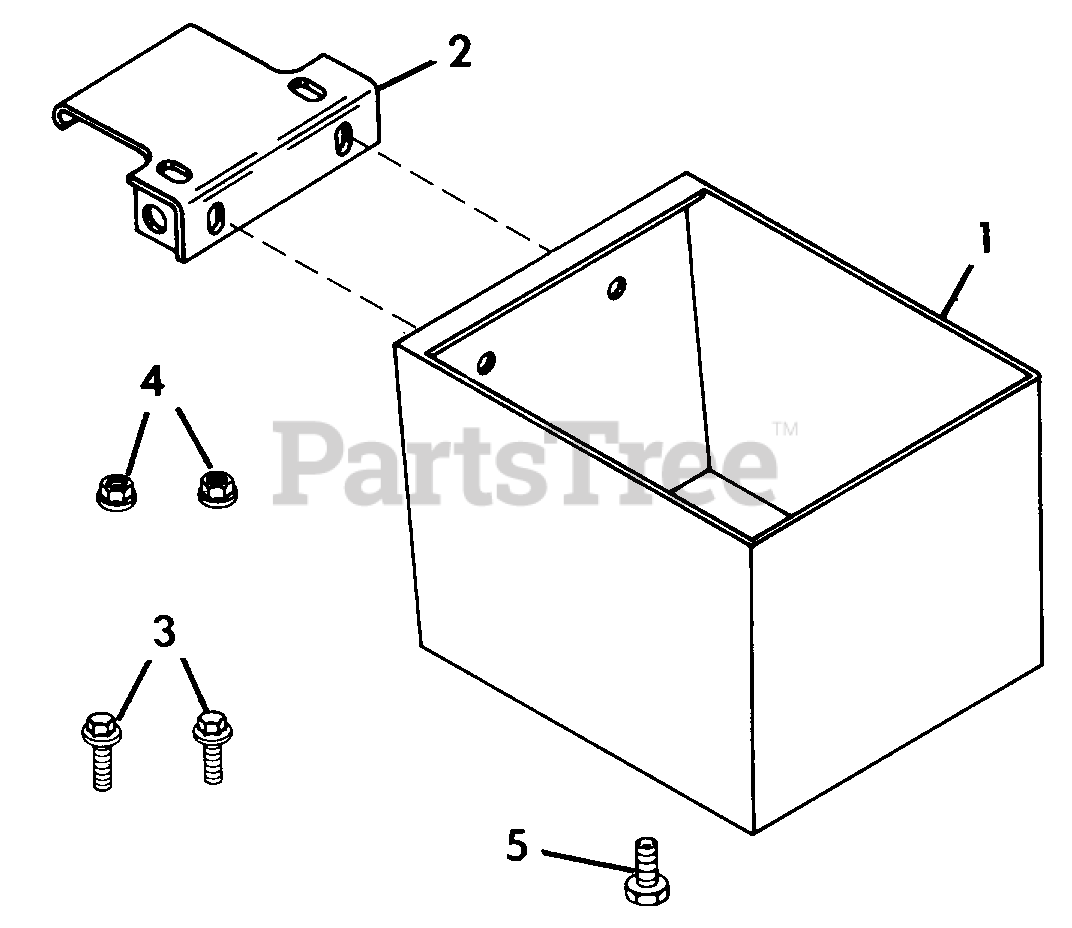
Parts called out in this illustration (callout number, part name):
1	BOX, WEIGHT
2	HOOK, MOUNT
3	SCREW, FLANGE 5/16-18 X .625
4	NUT, LOCK 5/16-18
5	BOLT, HEX 1/2-13 X 1.00
